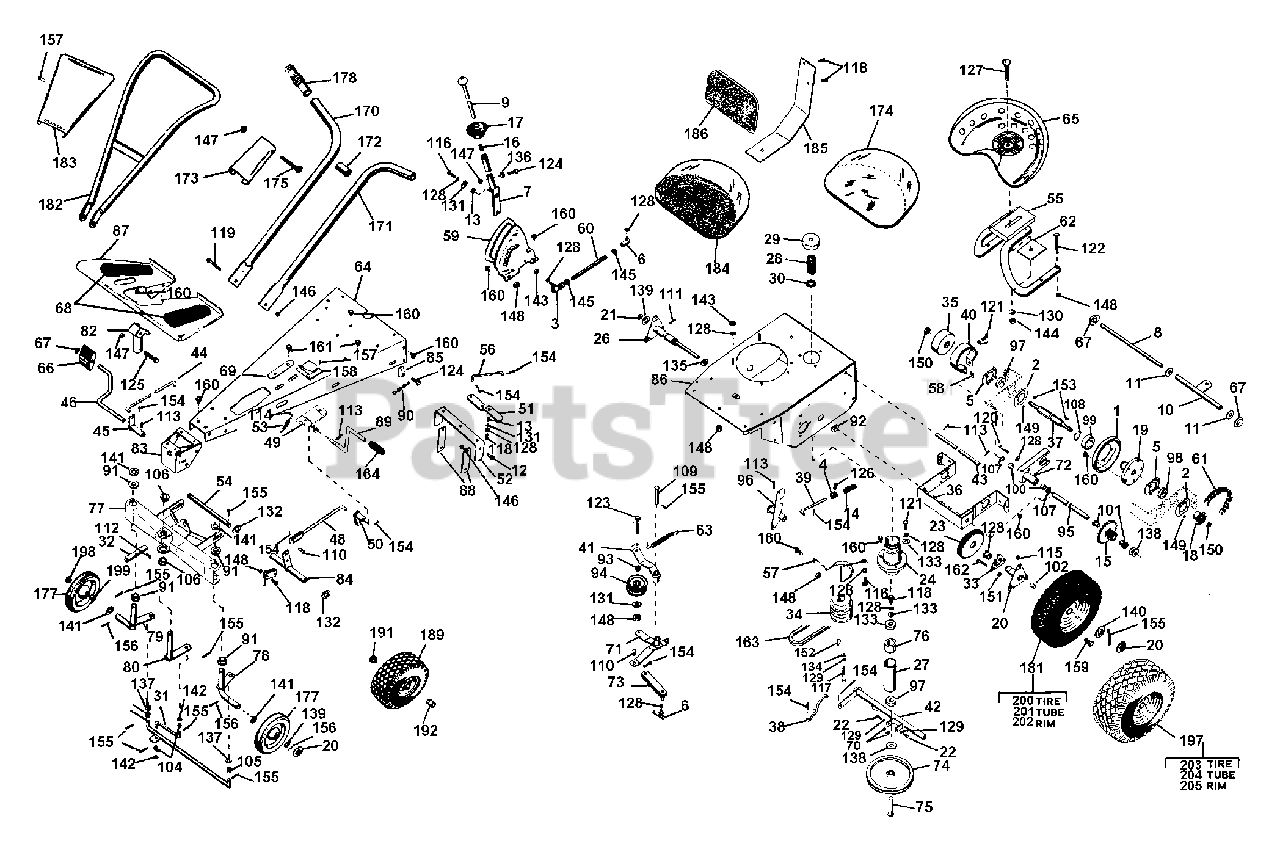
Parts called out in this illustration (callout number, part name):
1	FRICTION DISC
2	BEARING FLANGE
3	SNAP IN BALL JOINT
4	SET COLLAR
5	BEARING FLANGE
6	BALL JOINT
7	SHIFT LEVER
8	HITCH SHAFT
9	SHIFT RELEASE HANDLE
11	WAVE WASHER .531X.781X.125FH
12	SHOULDER BOLT .50 X .281
13	SPACER BUSHING .5 X .32 X .21
14	BRAKE SPRING
15	PINION & SPROCKET
16	SPRING
17	SHIFT BALL
18	9 TOOTH SPROCKET
19	FRICTION DISC HUB
20	HUB CAP
21	PUSHNUT
22	SCREW PIN
23	Differential Assembly
24	DRIVE SPRING HOUSING
25	L H AXLE
26	R H AXLE
27	DRIVE SPINDLE HOUSING
28	SPRING
30	SPRING RETAINER
31	STEERING LINK
32	AXLE PIVOT PIN
33	SUPPORT, BEARING
34	ENGINE SHEAVE
35	BRAKE DRUM
36	CARRIER
37	HEX SHAFT
39	BRAKE ROD
40	BRAKE BAND
41	IDLER ARM
42	DISK FORK
43	DISC FORK ROD
44	FRONT CLTCH ROD
46	PEDAL
47	FRONT LINK
48	MOWER CLTCH LINK
49	MOWER CLUTCH BRACKET
50	MOWER OVERCENTER LEVER
51	CLTCH TRANSFER LEVER
52	HANGER BRACKET
53	SPRING
54	HANGER PIN
55	SEAT BRACKET
56	REAR CLTCH ROD
57	REAR BELT FINGER
58	BRAKE BAND WASHER
59	SHIFT CNTL
60	SHIFT LINKS
61	CHAIN
62	SEAT SUPPORT WASHER
63	IDLER SPRING
64	FRAME CHANNEL
65	SEAT
67	CAP, .50 ROD YWZC
68	FOOT PAD
69	GUIDE PLATE
70	SPRING WASH
71	SHIFT TRANSFER LEVER
72	SLIDING FORK
73	SHIFT LINK
74	DRIVE DISK
75	DRIVE SPINDLE
76	BEARING SPACER .87 X .63 X 1.2
77	FRONT AXLE ASSM
78	L H WHEEL SPINDLE
79	R H WHEEL SPINDLE
80	CENTER STEER COL
81	TIE ROD
82	STEER BLOCK
83	FRONT FRAME ASSM
84	MOWER CLUTCH LEVER
85	BLADE BRAKE
86	REAR FRAME
87	FOOT REST
88	HANGER LINK
89	MOWER CLTCH PEDAL
90	BRAKE RELEASE CHAIN
91	FLANGE BUSHING
92	FLANGE BUSHING
93	SPCR, BRG .315X.50X.688X.281
94	IDLER
95	CARR SHFT
96	BRAKE BELLCRNK
97	BRG-BALL .625X1.375X.44
98	BRG-BALL .500X1.38X.437
99	BRG-BALL 1.25X2.18X.63
100	BSHG-SLV .625X.750X.500
101	BSHG-FLG .625X.750X.500X.875BR
102	BSHG-SLV .562X.625X.625 BRZ
103	BSHG-FLG.875X1X.625X1.250 BR
104	BSHG-FLG .372X.500X.312X.625NY
105	BSHG-FLG.500X.625X.312X.750NY
106	BSHG-FLG.750X1X.375X1.250 IC
107	SEAL .625X.875X.125
108	RG-RTNG-EXT 1.250X.050
109	PIN-CLEVIS .500 X 3.250
110	CLEVIS PIN
111	PIN-ROLL .188X1.25
112	PIN-ROLL .250X1.25
113	PIN-ROLL .250X1.25
114	PIN-GRV .188X.75 TP G
115	HYDRAULIC DRIVE FITTING
116	BLT-HEX .31-18X1.00 PL GR 2
117	BLT-HEX .25-20X.75 PL GR2
118	BLT-HEX .31-18X.63 PL GR 2
119	BLT-HEX .31-18X1.00 PL GR 2
120	BLT-HEX .31-18X1.00 PL GR 2
121	BLT-HEX .31-18X1.00 PL GR 2
122	BLT-HEX .38-16X1.00 PL
123	BLT-HEX .38-16X1.50 PL GR2
124	BLT-HEX .44-14X1.25 PL GR2
125	BLT-HEX .44-14X1.25 PL GR2
126	SCR-SET .25-20X.50 SQHCUP HT
127	BLT-RDHDSQNK .50-13X1.25 PL
128	WSHR-LK .312X.097 PL HVY
129	WSHR-LK .375X.115 HVY PL
130	WSHR-LK .500X.151 HVY PL
131	WSHR-FL-STL .38X.875X.083 PL
132	WSHR-FL-STL .531X1.062X.095 PL
133	BRG-CUP1.980X.420
134	WSHR-FL-STL .38X.875X.083 PL
135	WSHR-FL-STL .531X1.062X.095 PL
136	WSHR-FL-STL .531X1.062X.095 PL
137	BRG-NEEDLE .625X.812X.50
138	BRG-BALL .625X1.375X.44
139	WSHR-FL-STL .755X2.000X.125
140	BRG-CONE .750X.61
141	BRG-CUP 3.346X.532
142	WSHR-FL-STL .812X2.000X.148
143	NUT-JAM .375-16 PL
144	NUT-JAM .625-11
145	NUT-HEX .312-24 PL
146	NUT-LK-CTR .375-16 GR A PL
147	NUT-LK-CTR .250-20 PL
148	NUT-LK .312-18 GR A PL
149	NUT-KEPS 10-24 PL
150	NUT-LK-CTR .50-20 PL
151	NUT-LK-FLG .250-20 PL
152	KEY-WDRF .156X.625X.25 SAE 6
153	KEY-WDRF .188X.875X.375 SAE11
154	PIN-COTR .09X.75 PL
155	PIN-COTR .12X1.0 PL
156	PIN-COTR .09X.75 PL
157	RVT-POP.125 X .294 DOME
158	THROTTLE CONTROL
159	BRG-CUP 2.441X.562
160	BLT-SERHFWH .31-18X.50 PL
161	BLT-SCRHFWH .38-16X.50 PL
162	SCR-SLTR-SERNK .25-20X.62 PL
163	V-BELT, SAE 380-RAW EDGE
170	R H HANDLE BAR
171	L H HANDLE BAR
172	SPACER
173	HNDLBR PANEL
174	SEAT COVER
175	BLT-HEX .44-14X1.25 PL GR2
176	NUT-LK-CTR .312-24 PL
177	WHL 10 IN O.D.
178	GRIP
179	HEIGHT QUADRANT LABEL
180	MOWER IN-OUT LABEL
181	T/WHL ASSY
182	HANDLE BAR
183	HANDLE BAR PANEL
184	SEAT COVER
185	SEAT BACK SUPPORT
186	BACK REST
187	BLT-HEX .31-18X.63 PL GR 2
188	RVT-POP.125 X .294 DOME
189	FRONT WHEEL ASSEMBLY
190	PAPER GASKET
191	BSHG-FLG.750X1.125X1.250X1.312
192	BSHG-FLG .750X1.129X.750
193	BLT-HEX .31-18X.63 PL GR 2
194	WSHR-LK .312X.097 PL HVY
195	NUT-JAM .375-16 PL
196	MOWER IN-OUT LABEL
197	Tire and Wheel Assembly consisting of:(12M5)
198	BSHG-FLG.750X1.125X1.000X1.125
199	BSHG-FLG.750X1.125X1.000X1.250
200	TIRE 4.10/3.50X6 2PLY
201	TUBE
202	WHL 6 IN O.D.
203	TIRE 4.1/3.50X4
204	TUBE
205	WHL
